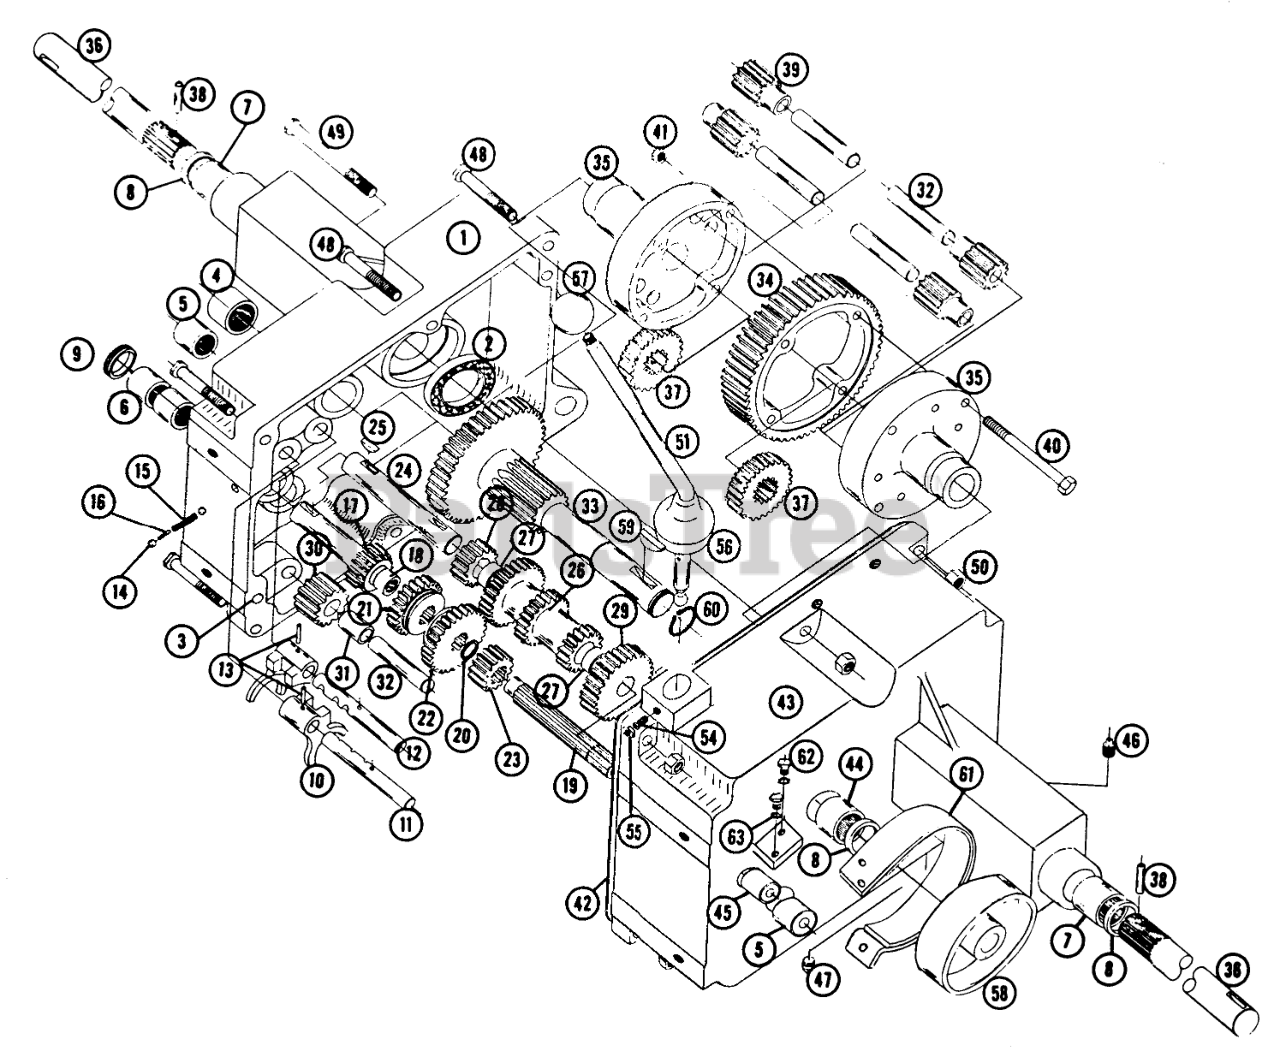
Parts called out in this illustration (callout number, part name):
3	PIN-DOWEL
4	BEARING-NEEDLE
5	BEARING-NEEDLE
7	BEARING-NEEDLE
10	FORK-SHIFT
11	RAIL-SHIFT
12	RAIL-REAR SHIFT
13	PIN-ROLL
14	BALL-DETENT
16	PIN-SHIFT
18	BEARING-NEEDLE
23	GEAR
25	Key
27	BUSHING-BRONZE
29	GEAR-CLUSTER SHAFT
30	GEAR/BUSHING ASM-REVERSE IDLER
31	BUSHING
32	PIN-DIFFERENTIAL
34	SVC BULLT 394
35	DIFFERENTIAL CASE
36	Axle-Rear
37	AXLE GEAR
42	GASKET-TRANSMISSION
46	Plug 1/4 Pipe
47	Plug 3/8 Pipe
48	Bolt, 3/8 16 x 2
49	Bolt Hex 3/8-16 x 1
54	SETSCREW
55	Nut 1/4-20
56	COVER-DUST
59	KEY-WOODRUFF
62	Bolt-1/4-20 x 5/8
63	Lockwasher
